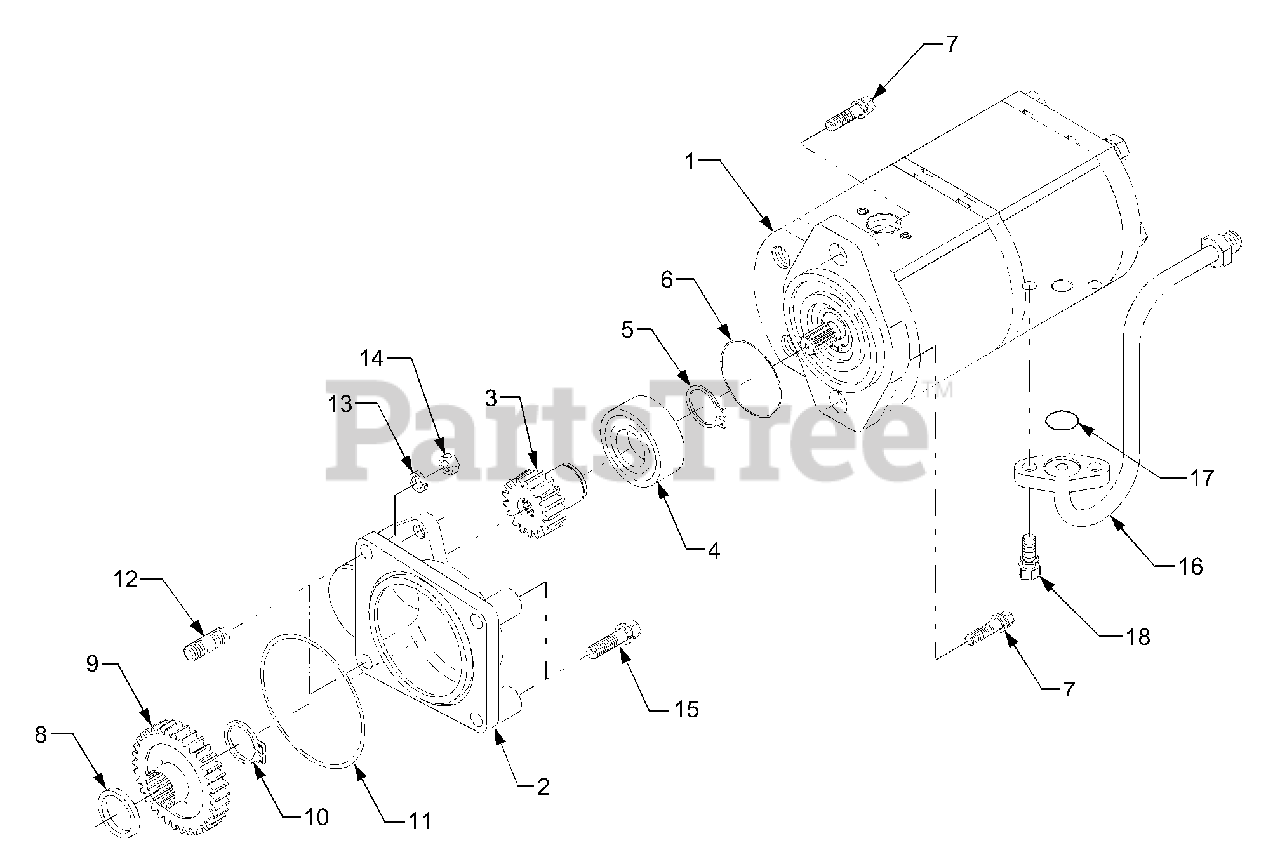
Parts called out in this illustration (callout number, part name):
1	Gear Pump Ass'y
2	Holder, Gear Pump
4	Bearing, Ball
5	Cir-clip, External
10	Cir-clip, External
13	Washer, Spring
16	Pipe 1, Steering
